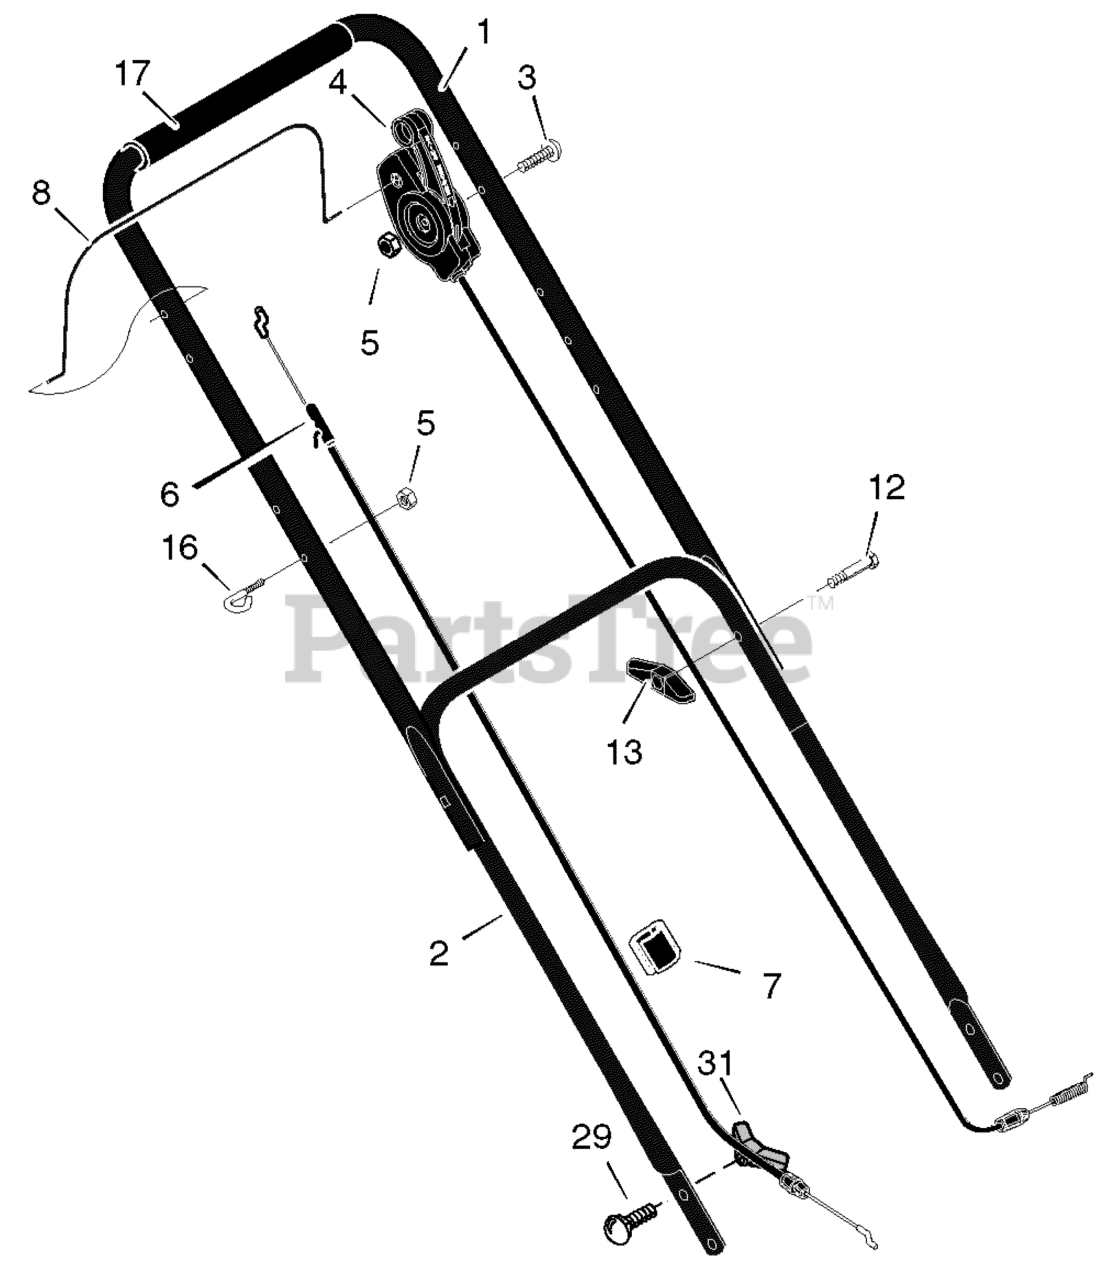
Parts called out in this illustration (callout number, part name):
1	Handle, Upper (Black)
2	Handle, Lower (Black)
4	Control, Drive
5	Locknut
6	Cable, Stop (Briggs)
7	Fastener, Double Cable
8	Lever, Stop
16	Guide, Rope
17	Tubing, Foam
29	Bolt, Carriage
31	Knob, Plastic
